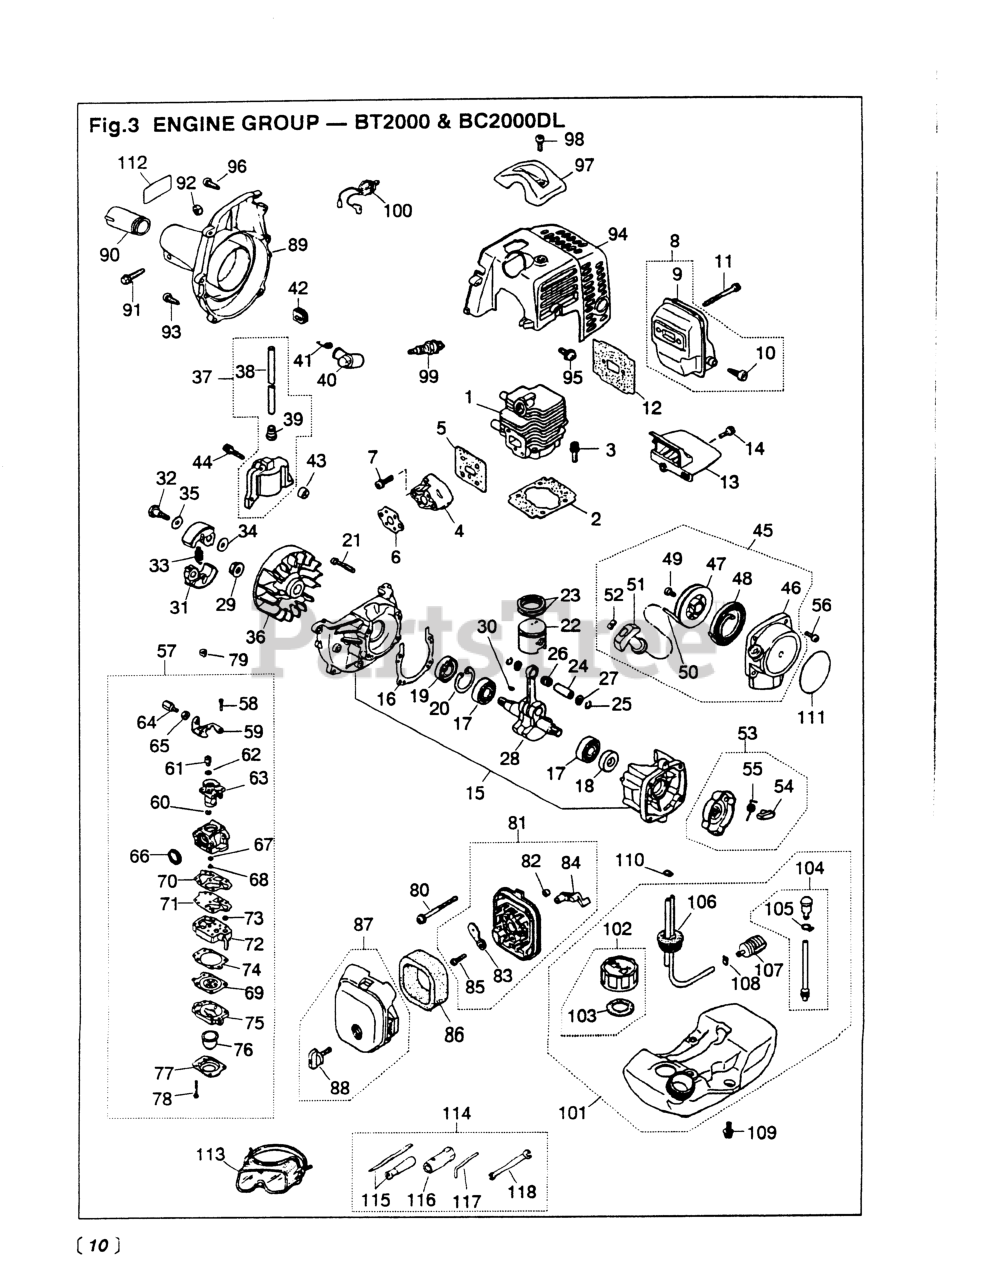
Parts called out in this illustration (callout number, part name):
1	CYLINDER
3	BOLT, M5 X 22
7	SCREW, M5X20 (RPLS.1400-75510)
9	MUFFLER ASSY (USE 5913-15100)
10	ARRESTER (RPLS 5850-15140)
11	BOLT, M5 x 50
12	GASKET, MUFFLER
14	SCREW, M4 X 16
15	CRANKCASE
17	BEARING
18	SEAL, OIL (RPLS 1100-21210)
19	SEAL, OIL (RPLS 1140-21220)
20	RING, SNAP, M28 x 1.2
21	SCREW, M5 x 30(RPLS 0263-00530
24	PIN, PISTON 5x8x26
25	RING, SNAP (RPLS 1101-41320)
27	WASHER
30	KEY
32	BOLT
34	WASHER, FLAT (USE 182303)
38	CORD
39	CAP
41	SPRING
42	GROMMET
44	BOLT
45	RECOIL ASSEMBLY
46	CASE
47	REEL
48	SPRING, SPIRAL
49	SCREW (RPLS -75150)
51	KNOB
52	PLATE, STOPPER
53	PULLEY ASSY (RPLS -75210)
54	RATCHET (RPLS 1850-75220)
55	SPRING, RETURN
56	SCREW, M4 X 16
58	SCREW
60	RING
61	SWIVEL
62	WASHER
63	VALVE ASSY (USE -81151)
64	SCREW, CABLE ADJUSTER
65	NUT, CABLE ADJUSTER
66	RING, PACKING
67	RING, O
69	DIAPHRAGM (USE 4810-81260)
70	GASKET, PUMP
71	DIAPHRAGM
72	BODY, PUMP
74	GASKET, DIAPHRAGM
75	BODY, PURGE
76	PUMP, PRIMING
77	COVER, PUMP
78	SCREW
79	CAP, CABLE END
80	SCREW, M5 X 55
82	SLEEVE
84	LEVER, CHOKE
85	SCREW (REPLACES 50030272)
86	ELEMENT
89	HOUSING COMPLETE
91	BOLT, M6x35 (RPLS -50635)
92	NUT, M6 X 5
93	SCREW, M5X20 (RPLS.1400-75510)
95	SCREW, M5 x 12
96	SCREW, HOUSING
97	GUARD, PLUG
98	SCREW, M5 X 12
100	SWITCH
103	PACKING
105	CLIP
106	PIPE COMPLETE
107	FILTER ASSY
108	CLIP (REPLACES 2841-31280)
109	SCREW
110	CLIP
112	LABEL, FAN COVER
114	TOOL SET
115	SCREWDRIVER
116	SOCKET, HEX, 3/4
117	BAR
118	SPANNER, 8 X 10 (RPLS 2540- )
